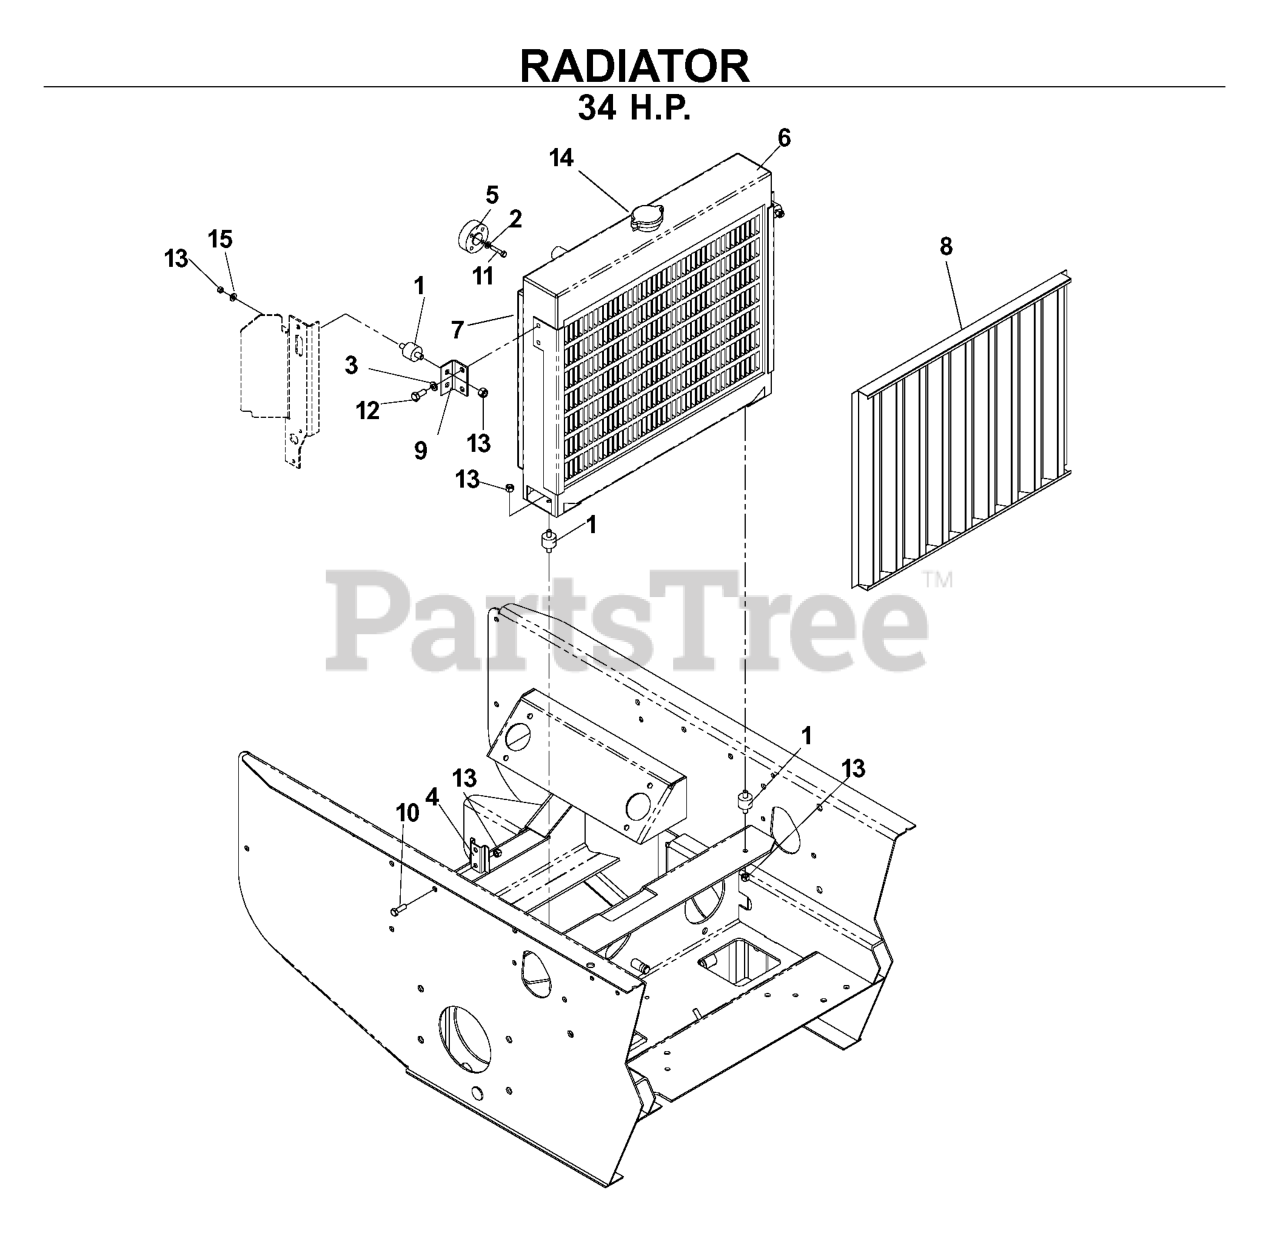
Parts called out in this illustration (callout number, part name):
2	LOCKWASHER 1/4"
3	WASHER.LOCK.HVY.HLCL.SPR.5/16
4	MOUNTING BRACKET
5	SPACER FAN
8	DEBRIS GUARD
9	BRACKET ISO
10	HCS 5/16C X 1
12	HCS 5/16C X 3/4
13	NUT 5/16 NYLOC
14	RADIATOR CAP
15	FLAT WASHER 5/16 SAE
539106326	LOWER HOSE
539106402	OVERFLOW TANK ASM
